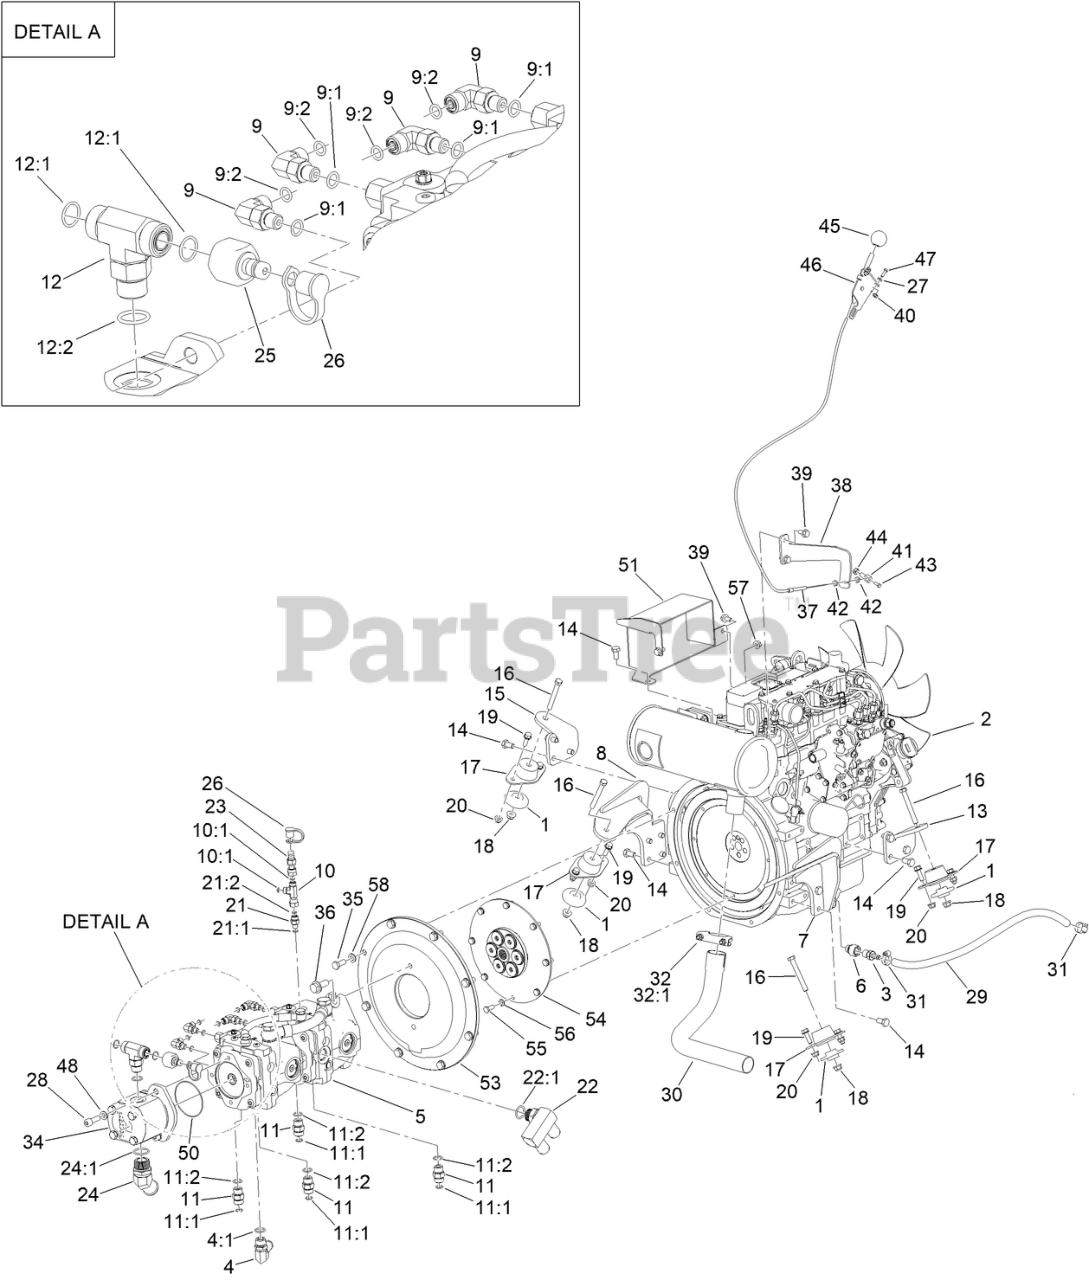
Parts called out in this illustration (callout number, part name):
1	SUPPORT-ISOLATOR
2	ENGINE-YANMAR 3TNV80F-NXDTR2
3	FITTING,MALE
4	FITTING-90
4:1	O-RING
5	PUMP - TANDEM
5:1:1	SEAL KIT
5:3:1	SHAFT SEAL KIT
5:4:1	TANDEM CONNECTION KIT
5:6:1	BOLT-HEX
5:6:2	Washer
5:6:3	O-RING
5:12:1	SWASH PLATE
5:13:1	Valve Plate
6	ADAPTOR-STR
7	LEFT HAND MOUNT [BLACK]
8	RIGHT HAND MOUNT [BLACK]
9	FITTING-ELBOW, 90 DEG
9:1	O-RING
9:2	O-RING
10	FITTING-HYD
10:1	O-RING
11	FITTING-STRAIGHT
11:1	O-RING
11:2	O-RING
12	TEE-ADAPTER
12:1	O-RING
12:2	O-RING
13	BRACKET-ENGINE MOUNT, REAR LH
14	SCREW-HH
15	BRACKET-ENGINE MOUNT, REAR RH
16	SCREW-HH
17	MOUNT-ENGINE
18	NUT-HF, NI
19	SCREW-HHF
20	NUT-HF, NI
21	FITTING-STRAIGHT
21:1	O-RING
21:2	O-RING
22	FITTING
22:1	O-RING
23	NIPPLE-TEST
24	FITTING-45 ELBOW
24:1	O-RING
25	NIPPLE
26	CAP-DUST
27	WASHER-FLAT
28	SCREW-HSH
29	HOSE-FUEL
30	PIPE-EXHAUST
31	CLAMP-WORM
32	CLAMP-MUFFLER
32:1	NUT-JAM
34	PUMP-HYDRAULIC
35	SCREW-HH
36	SCREW-HHF
37	THROTTLE CABLE
38	BRACKET-THROTTLE CABLE
39	SCREW-HHF
40	NUT-KEPS
41	SWIVEL-THROTTLE
42	NUT-JAM
43	SCREW-HH
44	NUT-LOCK, NI
46	LEVER-CONTROL
48	WASHER-HARDENED
50	O-RING
51	SHIELD-EXHAUST [BLACK]
53	COVER-FLYWHEEL
54	COUPLER-FLYWHEEL
55	SCREW-HH
56	WASHER-LOCK
57	NUT-HF
58	WASHER-FLAT
